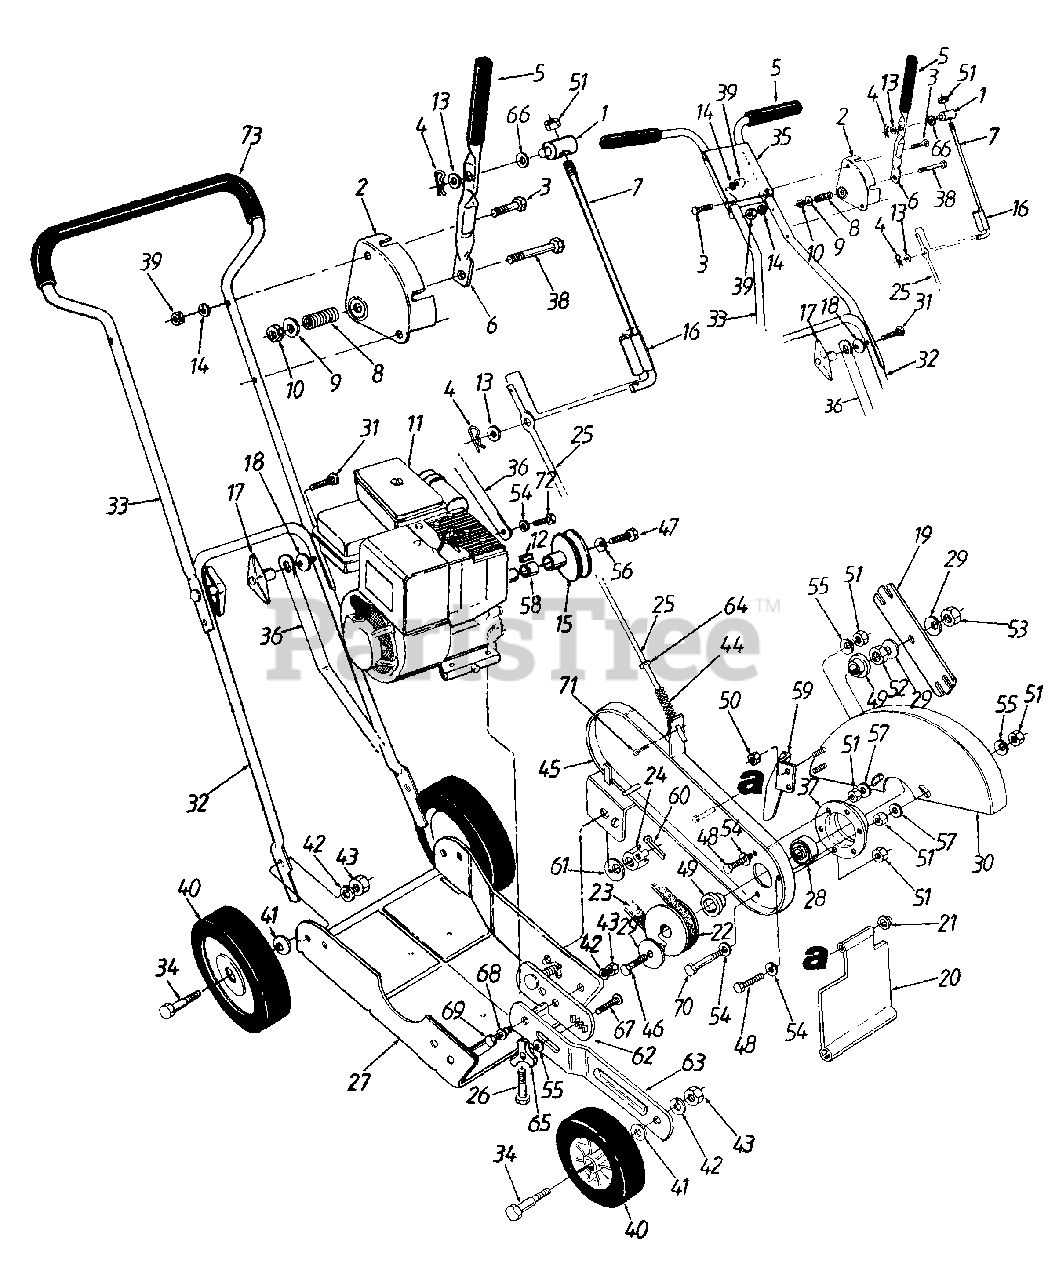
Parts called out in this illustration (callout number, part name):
1	Ferrule
4	Hairpin Clip
5	Foam Grip
7	Upper Clutch Rod
8	Compression Spring 1.38" Lg.
9	Fl-Wash. .344" I.D.
10	Hex L-Nut 5/16-18 Thd.
11	Engine
12	Sq. Key 3/16" x 1" Lg.
13	Fl-Wash. .344" I.D.
14	L-Wash. 1/4" I.D.
15	Engine Pulley
16	Clutch Rod Lock
17	Wing Nut Ass'y.
18	Saddle Wash. .32" I.D. x .937" O.D.
20	Edger Guide Flap
21	Push Cap
22	3/8" "V"-Pulley
23	"V"-Belt
24	Hex Slotted Nut 1/2-20 Thd.
25	Lower Clutch Rod
26	Hex L-Wash. TT-Tap Scr. 3/8-16 x 1" Lg.
29	Bell-Wash. 5/8" I.D. x 1-1/4" 0.0.
34	Shld. Bolt 3/8-16 Thd.
38	Hex Bolt 5/16-18 x 2" Lg.
39	Hex Nut 1/4-20 Thd.
40	Wheel Ass'y.
41	Bell-Wash. .38" I.D. x .88" O.D.
42	L-Wash. 3/8" I.D.
43	Hex Nut 3/8-16 Thd.
44	Comp. Spring 2" Lg.
47	Hex Bolt 3/8-24 x 1.5" Lg. (Gr. 5)
48	Hex Cap Bolt 5/16-18 x 1-1/4" Lg.
49	Shld. Spacer .626" l.D.
50	Hex Patch L-Nut 1/4-20 Thd.
51	Hex Nut 5/16-18 Thd.
52	Hex Jam Nut 5/8-18 Thd.
53	Hex Ins. L-Nut 5/8-18 Thd.
54	L-Wash. 5/16" I.D.
55	Bell-Wash. .345" I.D. x .88" O.D.
56	Bell-Wash. .396" I.D. x 1.14" O.D.
57	Fl-Wash. .312" I.D. x .75" O.D.
58	Spacer .748" I.D. x .985" O.D.
61	Bell-Wash. .515" I.D. x 1.14" O.D.
65	Hand Knob
66	Spring Wash. .32" I.D.
67	Carr. Bolt 5/16-18 x 1" Lg. (Special)
68	Spacer .383" I.D. x .503" O.D.
69	Hex Bolt 3/8-16 x 1" Lg.
70	Shld. Bolt 5/16-18 x 1.27" Lg.
71	Cotter Pin 1/8" Dia. x 1" Lg.
72	Hex Bolt 5/16-24 x .62" Lg.
73	Foam Grip
